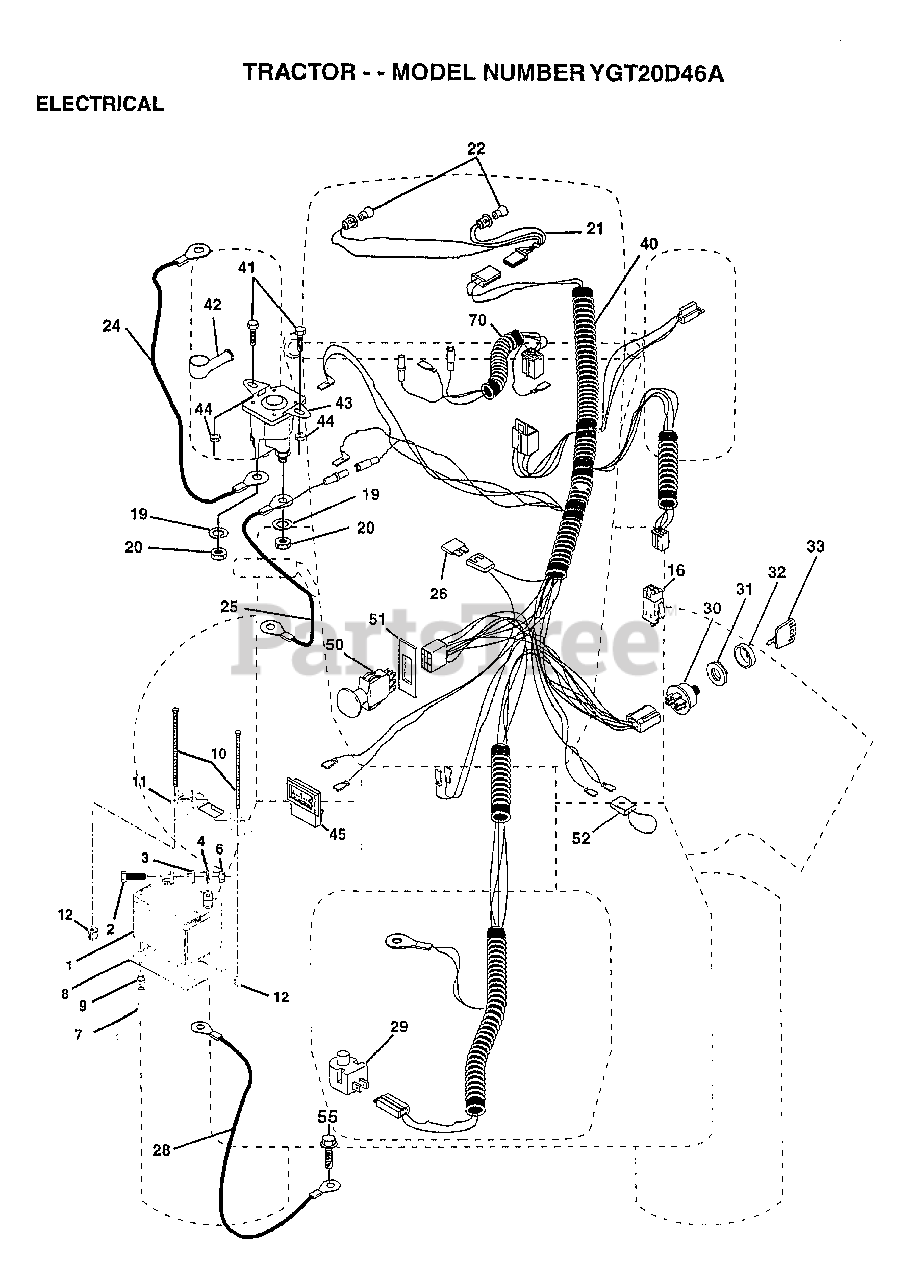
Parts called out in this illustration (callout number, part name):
2	BOLT LT
3	WASHER
4	LOCKWASHER
7	"DRAIN TU T, BATT"
8	"TRAY T, BATTERY"
9	HOSE CLAMP T
11	HOLDDOWN BATTERY
16	SWITCH INTERLOCK
20	NUT
21	HARNESS.ASM.HDLIG
22	HEADLAMP BULB
24	"CABLE T, BATTERY"
25	CABLE.6GA.22W/16W
26	FUSE HYT
28	CABLE.GRND.6GA.21
29	SWITCH SEAT
30	SWITCH IGN 4POS
31	NUT IGNITION
32	COVER KEY SWITCH
33	KEY
40	HARNESS IGNITION
41	BOLT HXHD FIN
44	NUT HXKEP 1/4X20
45	AMMETER
50	PTO SWITCH.BLK
51	RING RETAIN PTO
52	PROTECTION LOOP
55	SCREW LT
70	HARNESS ENG B&S
